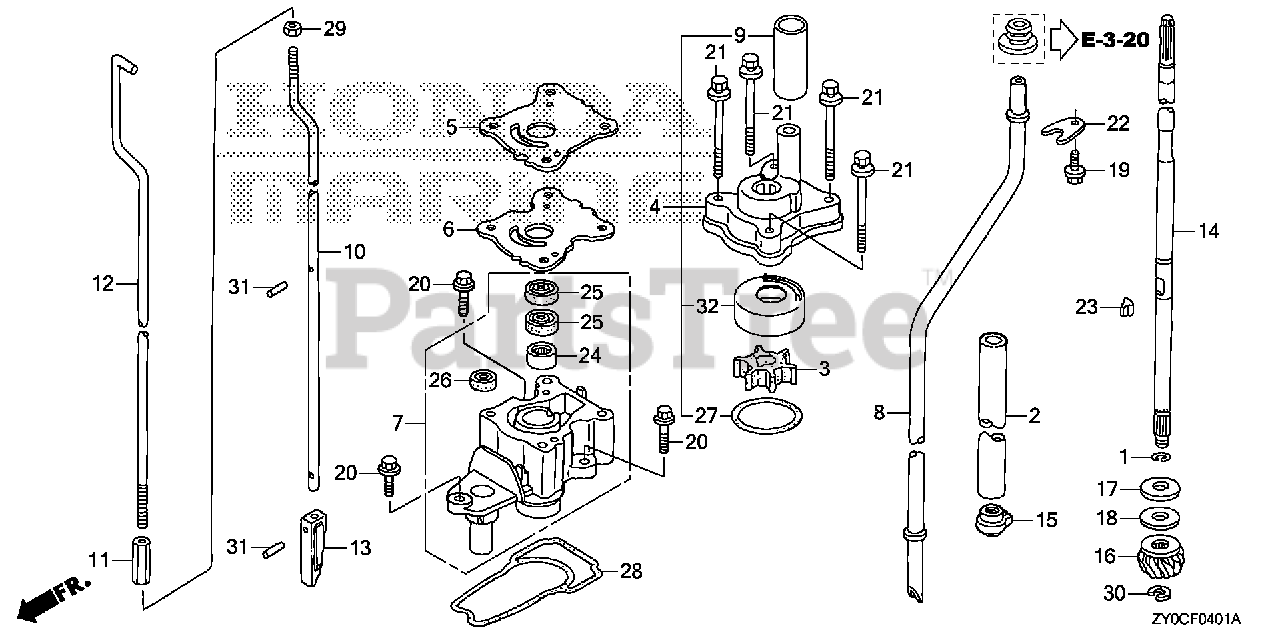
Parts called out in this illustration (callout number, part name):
1	CLIP, VALVE GUIDE
2	GUIDE, OIL (UL)
3	IMPELLER, PUMP (UL)
4	HOUSING ASSY., IMPELLER
5	COVER, IMPELLER
6	GASKET, IMPELLER
7	HOUSING, WATER PUMP (UL)
8	TUBE, WATER (UL)
9	RING, WATER TUBE SEAL
10	ROD B, SHIFT (UL)
11	JOINT, SHIFT ROD
12	ROD A, SHIFT (L)
13	ROD, PUSH
14	SHAFT, VERTICAL (UL)
15	SLINGER, OIL (UL)
16	GEAR, PINION
17	WASHER A, THRUST BEARING
18	WASHER B, THRUST BEARING
18	WASHER C, THRUST BEARING
19	BOLT, FLANGE (6X12) Use from Frame SN 1005249.
20	BOLT, FLANGE (6X20) (ENGINE NO.)
21	BOLT-WASHER (6X90)
22	PLATE, WATER TUBE SETTING
23	KEY, WOODRUFF
24	BEARING, NEEDLE (15X21X12)
25	SEAL, WATER (15X24X5)
26	SEAL, WATER (6MM)
27	O-RING (42.2X2.4)
28	O-RING, WATER PUMP HOUSING
29	NUT, HEX. (6MM)
30	E-RING (8MM)
31	ROLLER (2.5X11.8)
32	LINER, PUMP
